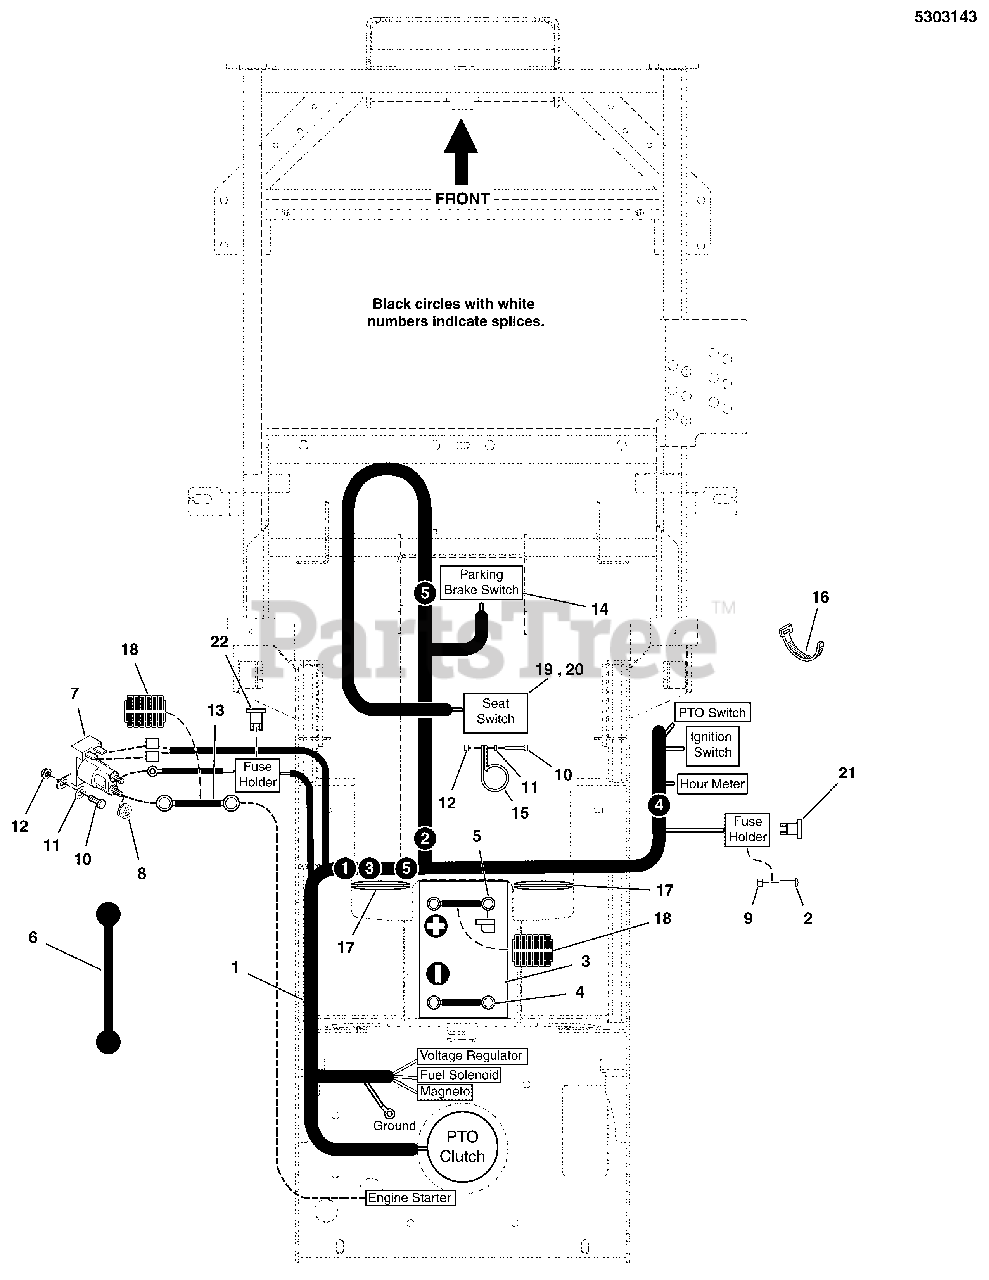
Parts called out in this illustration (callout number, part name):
1	HARNESS-WIRE
2	SCREW- #10-24 X 1/2 ROUND PHILLIPS
3	BATTERY, WET ( BCIU1, 350 CCA)
4	BATTERY CABLE, NEG, 14, 5/16-13/32
5	BATTERY CABLE, POS, 22, 1/4-5/16
6	STRAP-BLACK RUBB
8	NUT, HEX KEPS, 1/4-20
9	NUT, #10-24 HEX NYLON LOCK
10	BOLT, 1/4-20 X 3/4 GD5 CZ
11	WASHER, 1/4 SAE
12	NUT, 1/4-20 HEX SERR. FLANGE
13	BATTERY CABLE, POS, 22, 1/4-5/16
14	SWITCH, DP NO/NC SNAP-IN
15	CLAMP, VINYL INSULATED, 1.00
16	TIE,SELF-LOCKING, 6"
17	GROMMET, 2" ID
18	WIRE LOOM, 3/8 ID X 18 IN
19	SEAT SWITCH, MILSCO, BOLT-IN
20	SEAT SWITCH, MILSCO, TWIST-IN
21	FUSE, ATO-15 (15 AMP)
22	FUSE, ATO-20 (20 AMP)
